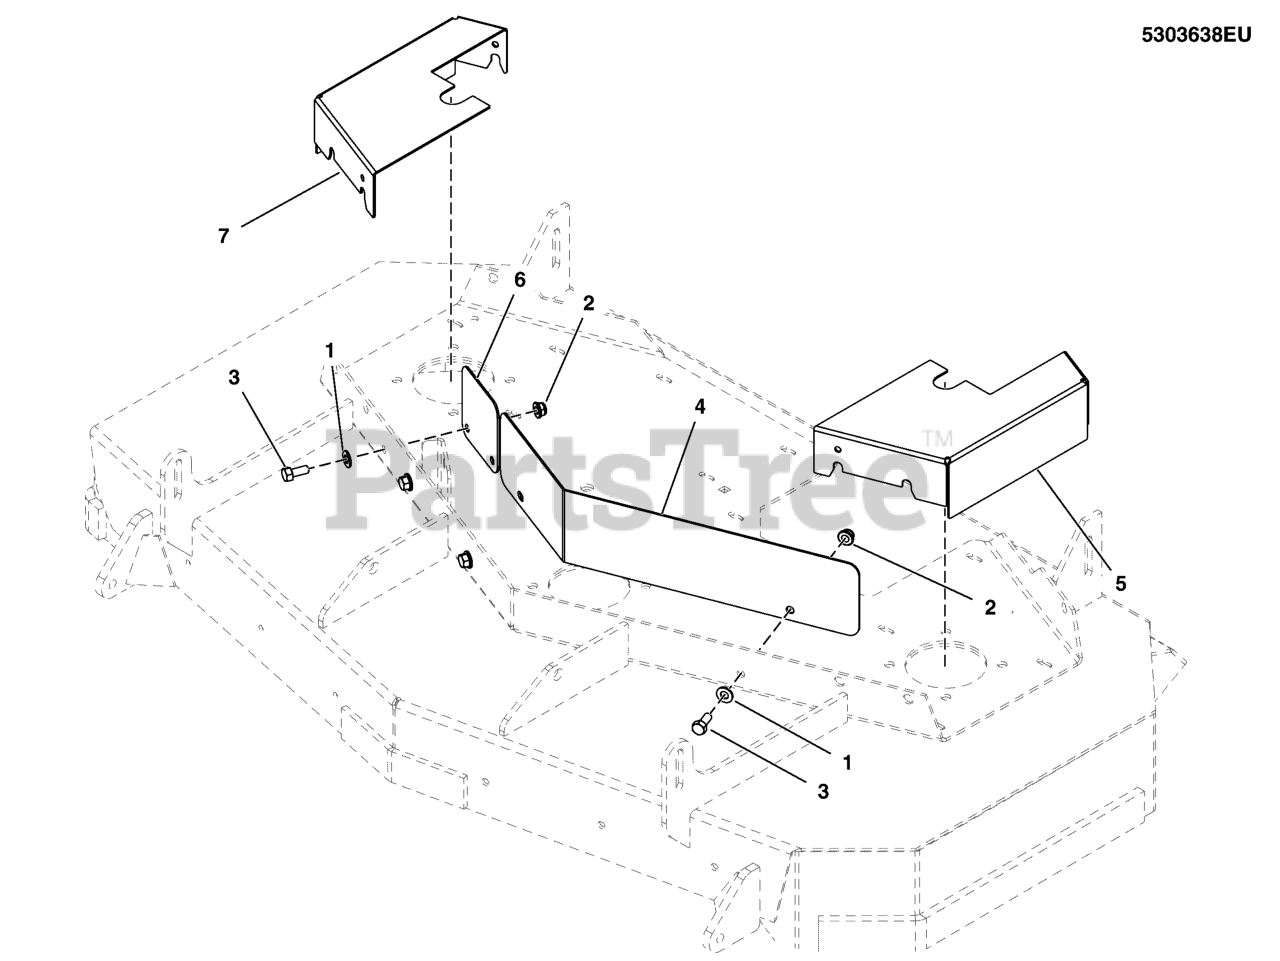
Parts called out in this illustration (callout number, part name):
1	WASHER, 5/16" SAE
2	NUT, 5/16-18 HEX NYLOCK FLANGE
3	BOLT, 5/16-18 X 3/4 GD5
4	PLATE, DECK GUARD, CENTER - RED
5	PLATE, DECK GUARD, LH - RED
6	PLATE, DECK GUARD, CENTER - RED
7	PLATE, DECK GUARD, RH - RED
